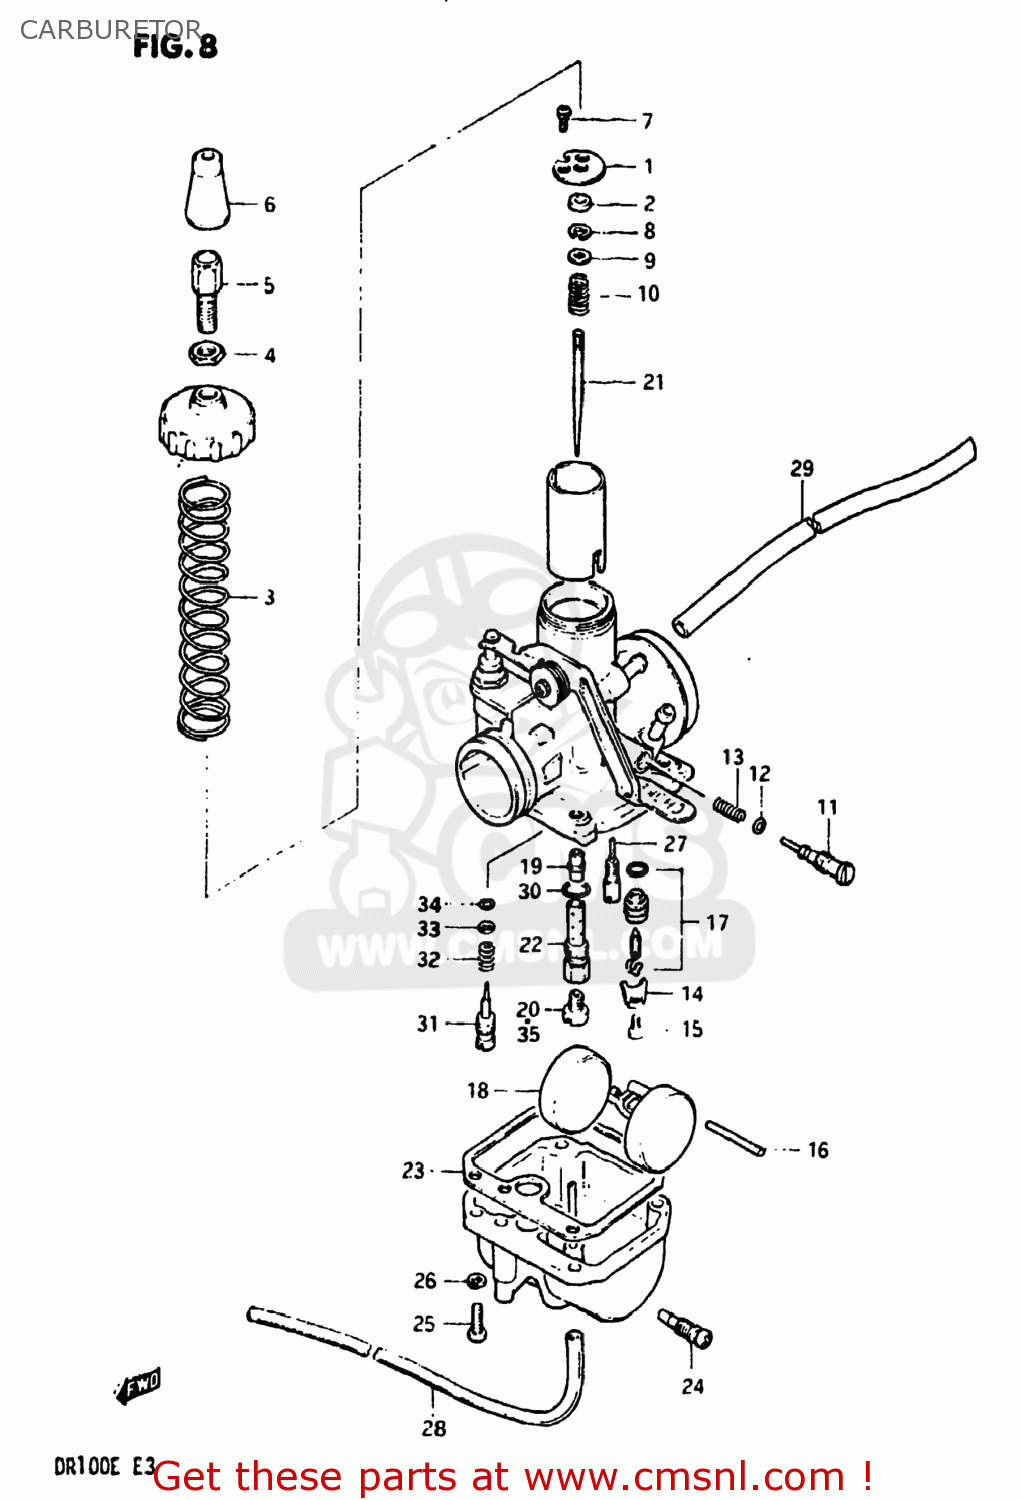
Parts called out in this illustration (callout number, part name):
1	PLATE,NEEDLE VALVE FITTING
2	RING
3	SPRING,THROTTLE VALVE
4	NUT
5	ADJUSTER,CABLE
6	CAP,RUBBER
7	SCREW
8	CLIP
9	WASHER,JET NEEDLE
10	SPRING
11	SCREW,THROTTLE STOP
12	O RING
13	SPRING
14	PLATE,NEEDLE VALVE FITING
15	SCREW
16	PIN,FLOAT
17	VALVE ASSEMBLY,NEEDLE
18	FLOAT
19	JET,NEEDLE
20	JET,MAIN(87.5)
21	NEEDLE,JET(5L8-3)
22	PIPE,BLEEDER
23	GASKET,FLOAT CHAMBER
24	PLUG,DRAIN
25	SCREW
26	LOCK WASHER
27	JET,PILOT(22.5)
28	HOSE
29	HOSE
30	O RING
31	SCREW,PILOT
32	SPRING
33	GASKET
34	O-RING
35	JET,MAIN
